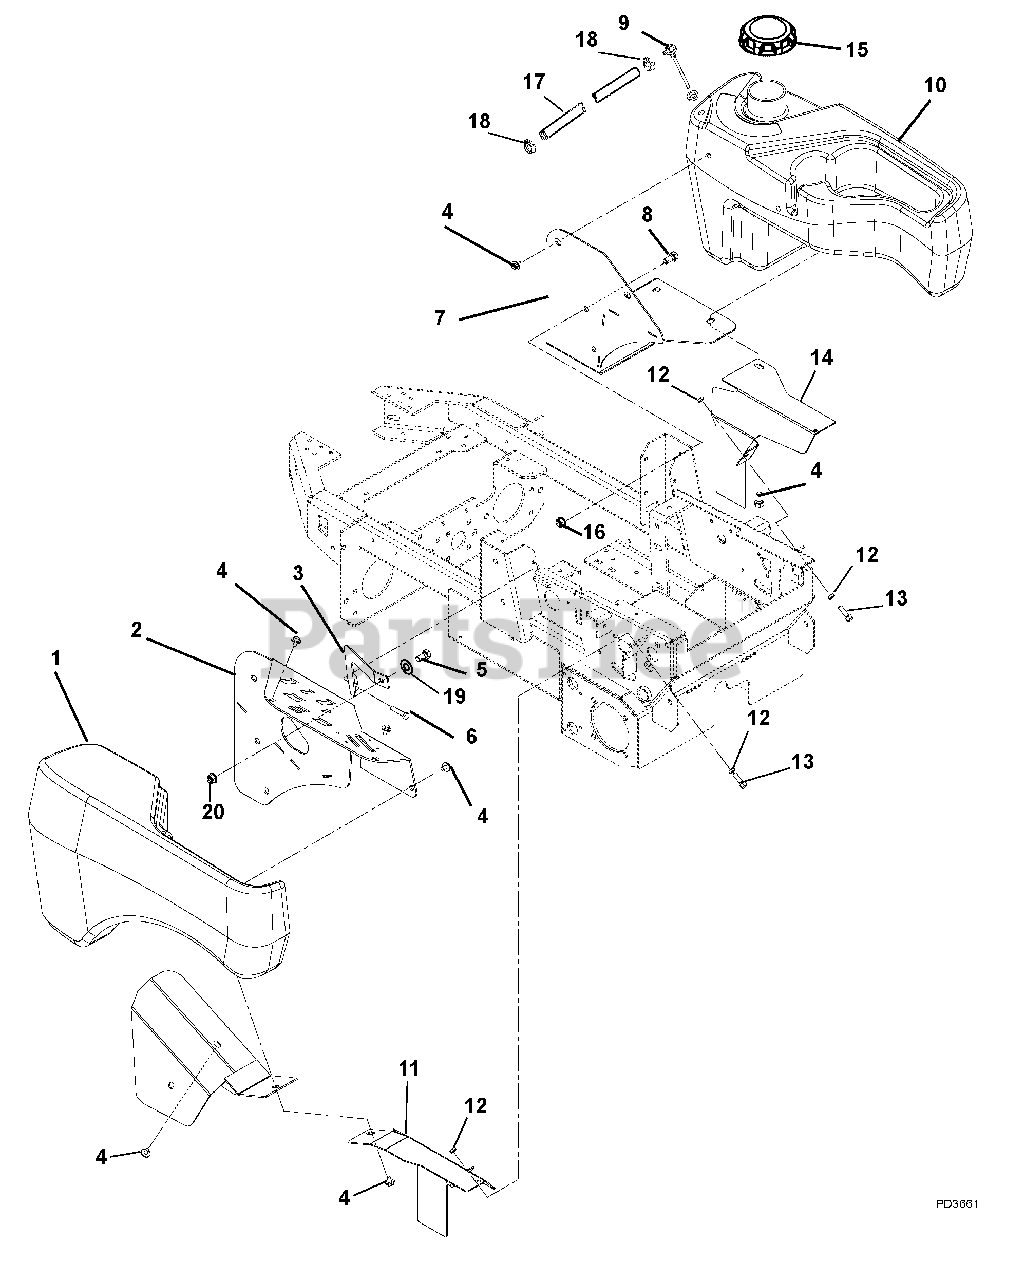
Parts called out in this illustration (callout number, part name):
1	Fender, Right Hand
2	Weldment, Control Panel
3	Stiffener, Fender
4	Bolt, SEMS .31-18 x .62
5	Bolt, Hex .38-16 x .75 Grade 5
6	Screw, Tapping .38-16 x .50 Hex Washer Head Thread Rolling
7	Weldment, Fuel Tank Bracket (Outfront)
8	Bolt, Hex .50-13 x 1.00 Grade 5
9	Assembly, Fuel Line and Fitting
10	Tank, Fuel Left Hand Outfront
11	Cover, Tire Right Hand
12	Nut, Hex-Jam .375-16
13	Bolt, Hex .38-16 x 1.25 Grade 5
14	Cover, Tire Left Hand
15	Cap, Fuel
16	Nut, .50-13 Nyloc Flange
17	Gas Line-Bulk 1/4" I.D.
18	Clamp, Hose Wire .490/.510 x .116
19	Washer, Flat-Steel .38 x .875 x .083
20	Nut, Flange .375-16
